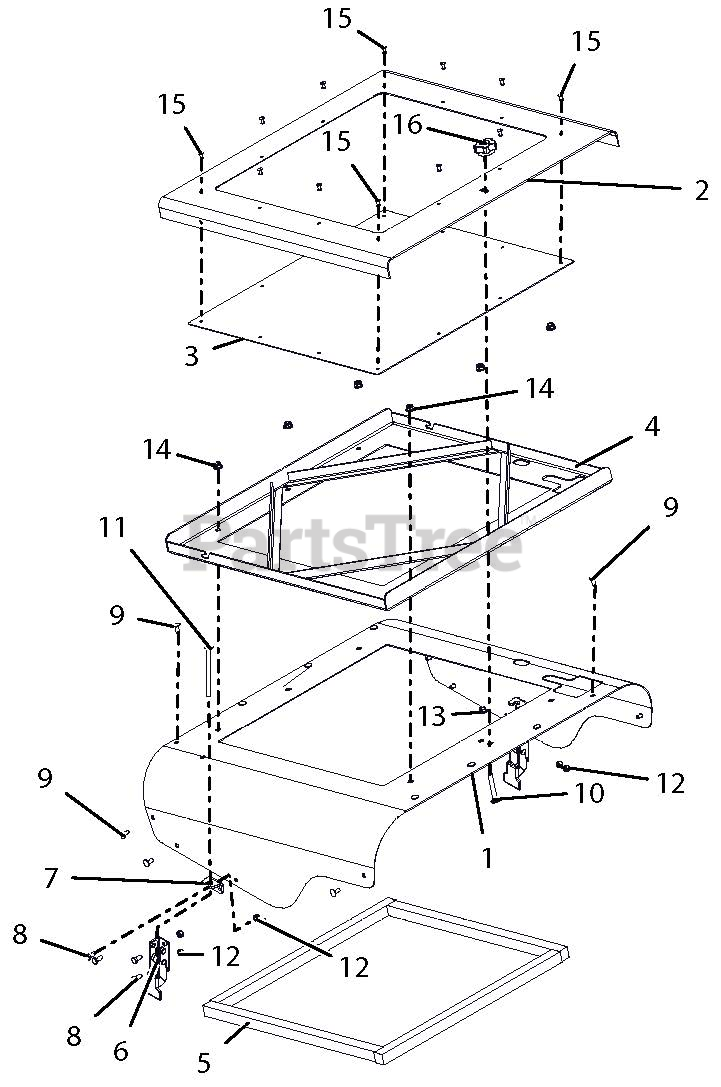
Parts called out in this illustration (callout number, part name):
1	HOOD, PT400 DIESEL
2	WLDMT, SCRN MOUNT
3	SCRN, DIESEL RADIATOR
4	WLDMT, DIESEL RADIATOR MOUNT
5	FOAM, ADHESIVE BACK, 19.00 X .875 X .875
6	LATCH, OVER-CENTER DRAW
7	BRKT, DRAW LATCH KEEPER
8	BLT-HEX .25-20X.63 GR5 BLKZC
9	BLT, RDHDSQNK .25-20 X .625 YWZC RED HEAD
10	BLT-RDHDSQNK .31-18X2.25 G5 Y
11	BLT-RDHDSQNK .31-18X4.50 FTH G5 Y
12	NUT-LK-CTR .25-20 YWZC
13	@NUT-SPNLK-FLG .312-18 YWZC
14	NUT-LK-NYL-FLG .31-18 YWZC
15	RVT-POP .187x.375 (#66)
16	KNOB, CLAMPING
